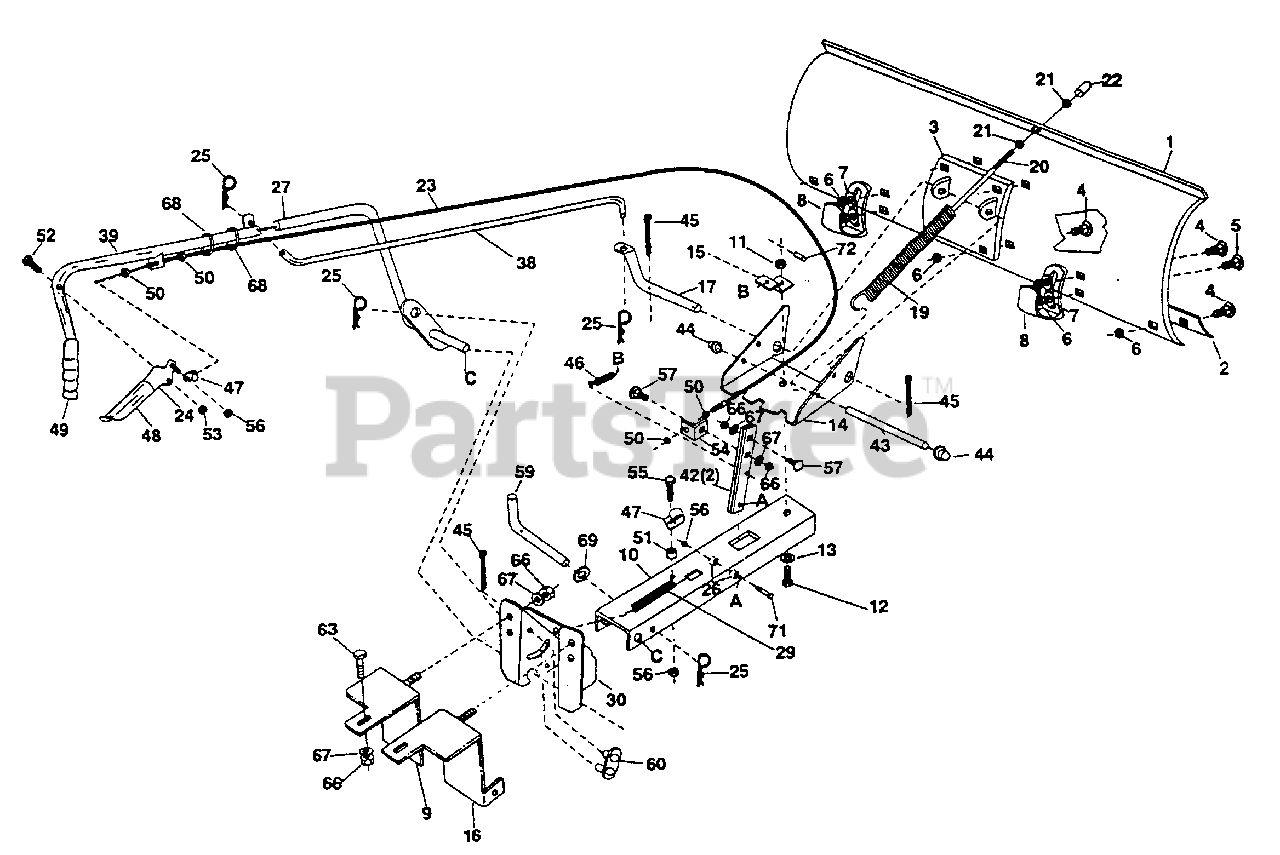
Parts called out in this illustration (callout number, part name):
1	Blade 42"
2	Wear Plate 42"
3	Reinforcement Plate Ass'y.
4	Bolt, Carriage 5/16-18 x 3/4"
5	Bolt, Carriage 5/16-18 x 1"
6	Nut, Hex Lock 5/16-18
7	Washer, 5/16"
8	Skid Shoe
9	Support Bracket (L.H.)
10	Ass'y. Channel Sub
11	Nut, Hex Lock 1/2-13
12	Bolt, Special Pivot
13	Washer, Flat 7/16"
14	Plate, Pivot 7 Ga.
15	Bracket, Spring Mt.
16	Support Bracket (R.H.)
17	Shaft Pivot
19	Spring, Blade Adjust
20	Bolt, Hex 3/8-16 x 3-1/2"
21	Nut, Hex 3/8-16
22	Plastic Cap
23	Control Cable Ass'y.
24	Release Grip Ass'y.
25	Pin, Hairpin Small 3/32"
26	Spacer, .28 I.D. x 1"
27	Lift Handle Rod Ass'y.
29	Extension Spring
30	Pivot Support Bracket
38	Rod, Blade Pivot
39	Ass'y. Lift Handle Tube
42	Angle Lock Bar
43	Spring Mount Rod
44	Palnut, 3/8"
45	Cotter Pin 1/8" x 1-1/4"
46	Angle Lock Spring
47	Cable End Fitting
48	Grip, Plastic
49	Handle, Grip 3/4"
50	Hex Jam Nut 5/16 Thread
51	Spacer
52	Hex Bolt, 5/16-18 x 1-1/2"
53	Hex Lock Nut 5/16-18 Thread
54	Cable Mount Bracket
55	Hex Bolt 1/4-20 x 1-1/4"
56	Hex Lock Nut 1/4-20 Thread
57	Carriage Bolt 3/8-16 1-1/4"
59	Pivot Channel Shaft
60	Lift Link Ass'y.
63	Hex Bolt 3/8-16 x 1"
66	Hex Nut 3/8-16 Thread
67	Lock Washer 3/8"
68	Plastic Tie
69	Washer
71	Bolt, Hex 1/4-20 x 3-1/4" Lg. (Gr. 5)
72	1/4" x 1" Spring Pin
